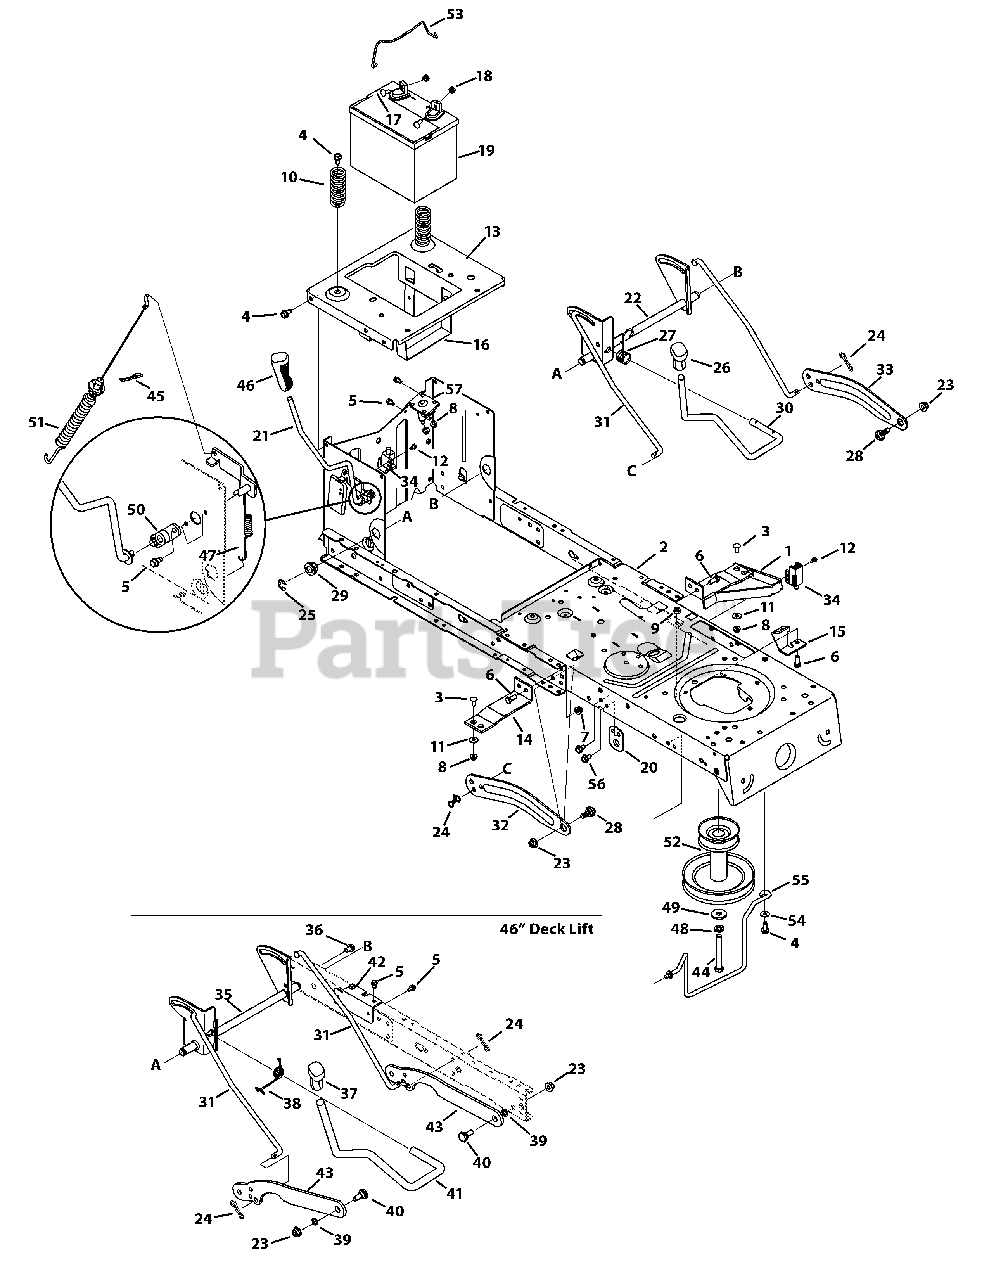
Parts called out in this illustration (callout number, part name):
1	Support Bracket
2	Frame Assembly
3	Screw Carriage, 1/4-20 x .62
4	Screw 5/16-18 x .750
5	Screw, 1/4-20 x .500
6	Hex Screw, 5/16-18 x .75
7	Flangelock Nut, 5/16-18
8	Flangelock Nut, 1/4-20
9	Hexlock Nut, 5/16-18
10	Compression Spacer, 1.28 x 3.125
11	Flat Washer, .28 x .74 x .063
12	Shoulder Spacer, 10-32 x .500
13	Seat Frame Bracket
14	Running Board Bracket
15	Support Frame Bracket
16	Battery Bracket
17	Hex Head Flange, 1/4-20 x .75
18	Sems Nut, 1/4-20
19	Battery, 230 CCA
20	Support Bracket
21	PTO Handle Assembly
22	Lift Assembly, 42"
23	Flangelock Nut, 3/8-16
24	Bow-tie Cotter Pin
25	E Ring
26	Handle Grip, 1/2
27	Torsion Springing
28	Shoulder Bolt, 3/8-16 x .625 x .175
29	Hex Flange Bearing
30	Deck Lift Handle
31	Lift Rod
32	42" Lift Arm, RH
33	42" Lift Arm, LH
34	Switch Interlock
35	Lift Assembly, 46"
36	Screw, 5/16-18 x .625
37	Handle Grip, 5/8
38	Torsion Spring Handle, 46"
39	Flat Washerer, .385 x .62 x .063
40	Shoulder Bolt, 3/8-16 x .500 x .270
41	46" Lift Handle
42	Frame Brace Bracket
43	Lift Deck Link
44	Hex Screw, 7/16-20 x 3.25
45	Click Pin
46	Handle Grip, 3/8
47	PTO Springing Extension
48	Regular Duty Washerer Lock, 7/16
49	Flat Washer, .450 x 1.250 x .164
50	PTO Bearing
51	Deck Engage Cable
52	Engine Pulley, 3.39 x 6.12
53	Battery Hold Down Rod
54	Flat Washer, .406 x .875 x .059
55	46" Belt Keeper
56	Screw, 5/16-18.0 x .625
57	12V Solenoid
